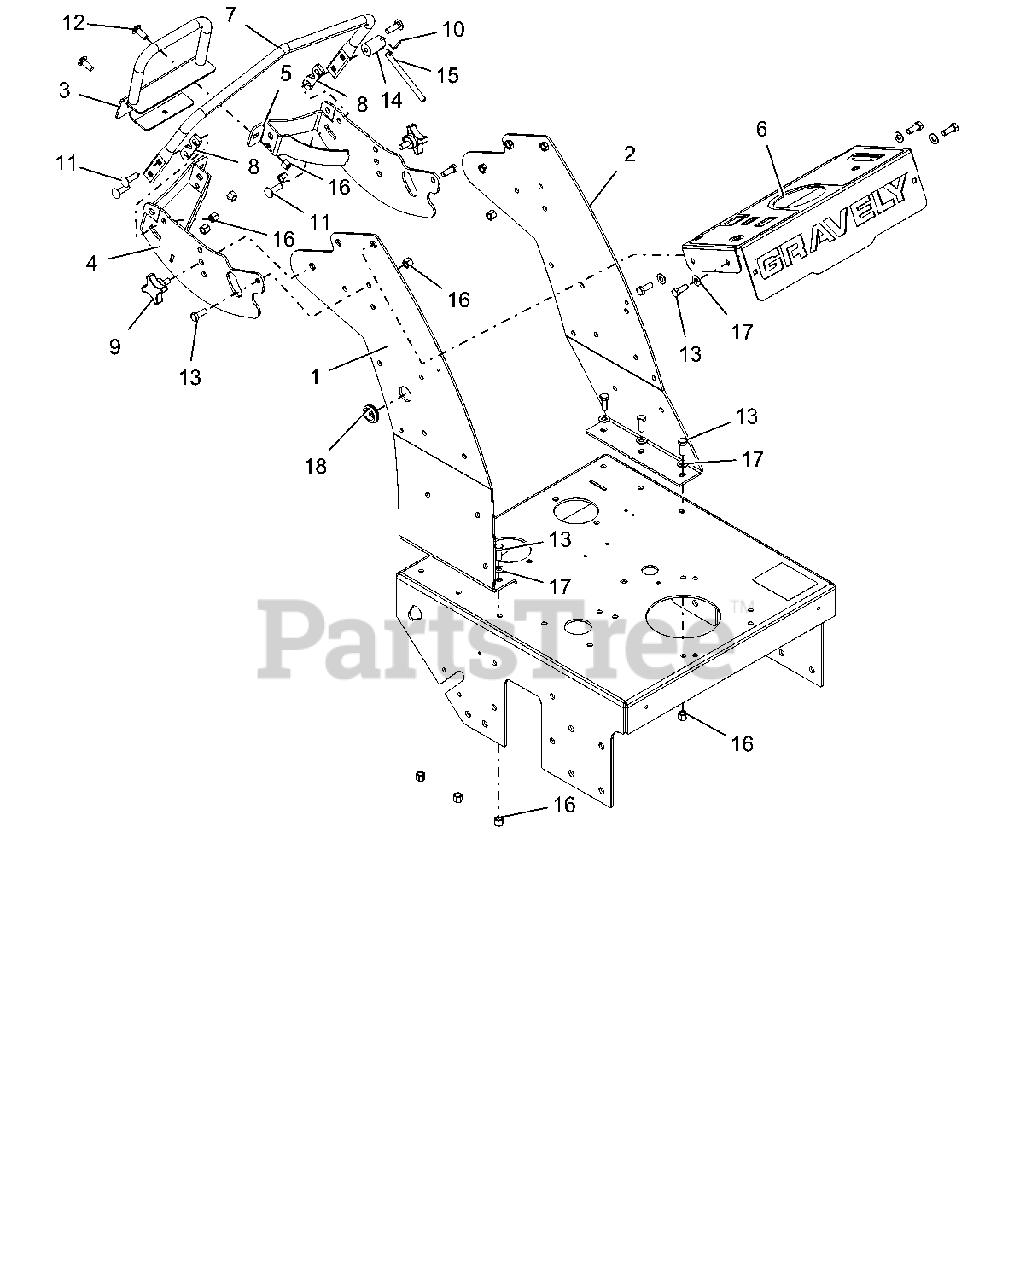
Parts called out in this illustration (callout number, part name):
1	WLDMT, RH UPRIGHT TOWER-RED
2	WLDMT, LH UPRIGHT TOWER-RED
3	WLDMT, REVERSE BAR (RED)
4	WLDMT, RH CONTROL MOUNT-RED
5	WLDMT, LH CONTROL MOUNT-RED
6	CONSOLE, W/ DECAL, GRV PS MY13
7	SUPPORT, HANDLE-RED
8	SHIM, BAR 5 DEG SPEED-RED
9	KNOB, 3/8-16 x .75
10	PIN, SPRING
11	BLT-RDHDSQNK .38-16X1.25 G5 YWZC
12	BLT-RDHDSHSQNK.38-16X1.0 G5YZ
13	BLT-HEX .38-16X1.00 GR5 YWZC
14	BASE, LOCK LEVER Y
15	LEVER, LOCK Y
16	NUT-LK-NYL .38-16 YWZC
17	WSHR-FL-STL.406X.812X.065 YWZ
18	GROMMET:RUB:.88IDx1.38ODX.14GR
